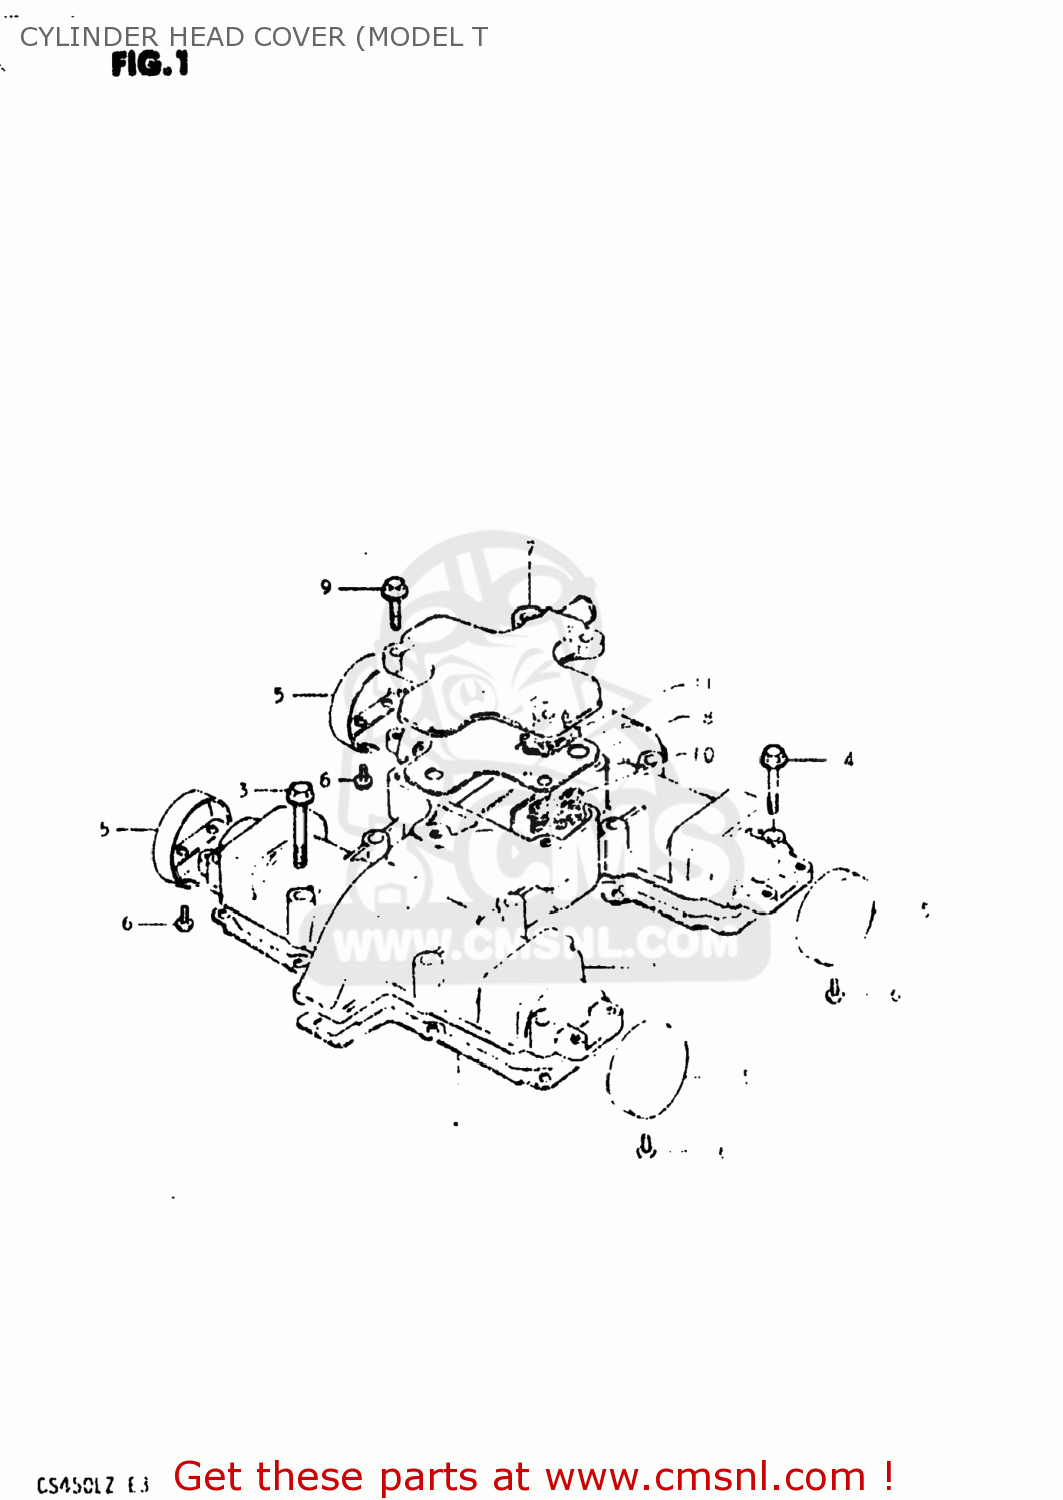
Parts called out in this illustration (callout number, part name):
1	COVER,CYLINDER HEAD
2	GASKET,CYLINDER HEAD COVER
3	BOLT
4	BOLT
5	CAP,CYLINDER HEAD COVER
6	SCREW
7	COVER,BREATHER
8	GASKET (MCA)
9	BOLT,REAR
10	COVER,BREATHER
11	SEPARATOR,OIL BREATHER
